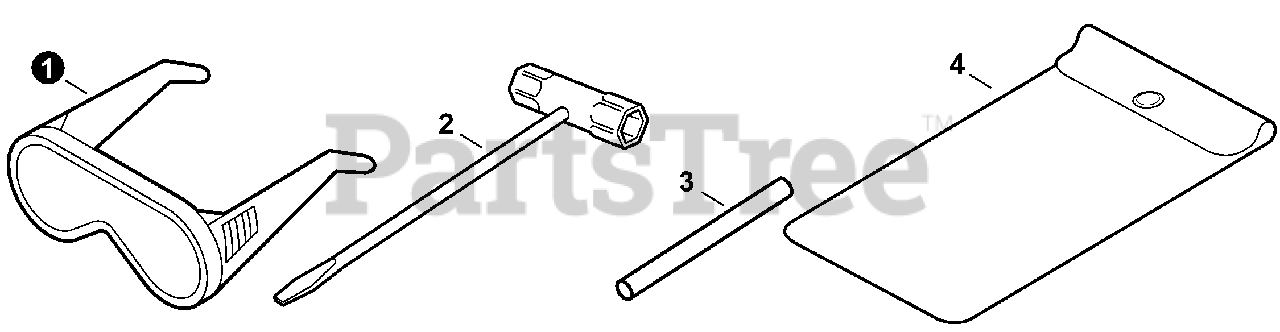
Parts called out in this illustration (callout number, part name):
1	GLASSES, SAFETY
2	T-WRENCH 17×19 L200
3	TOOL, LOCKING 5×120mm
4	BAG, TOOL
